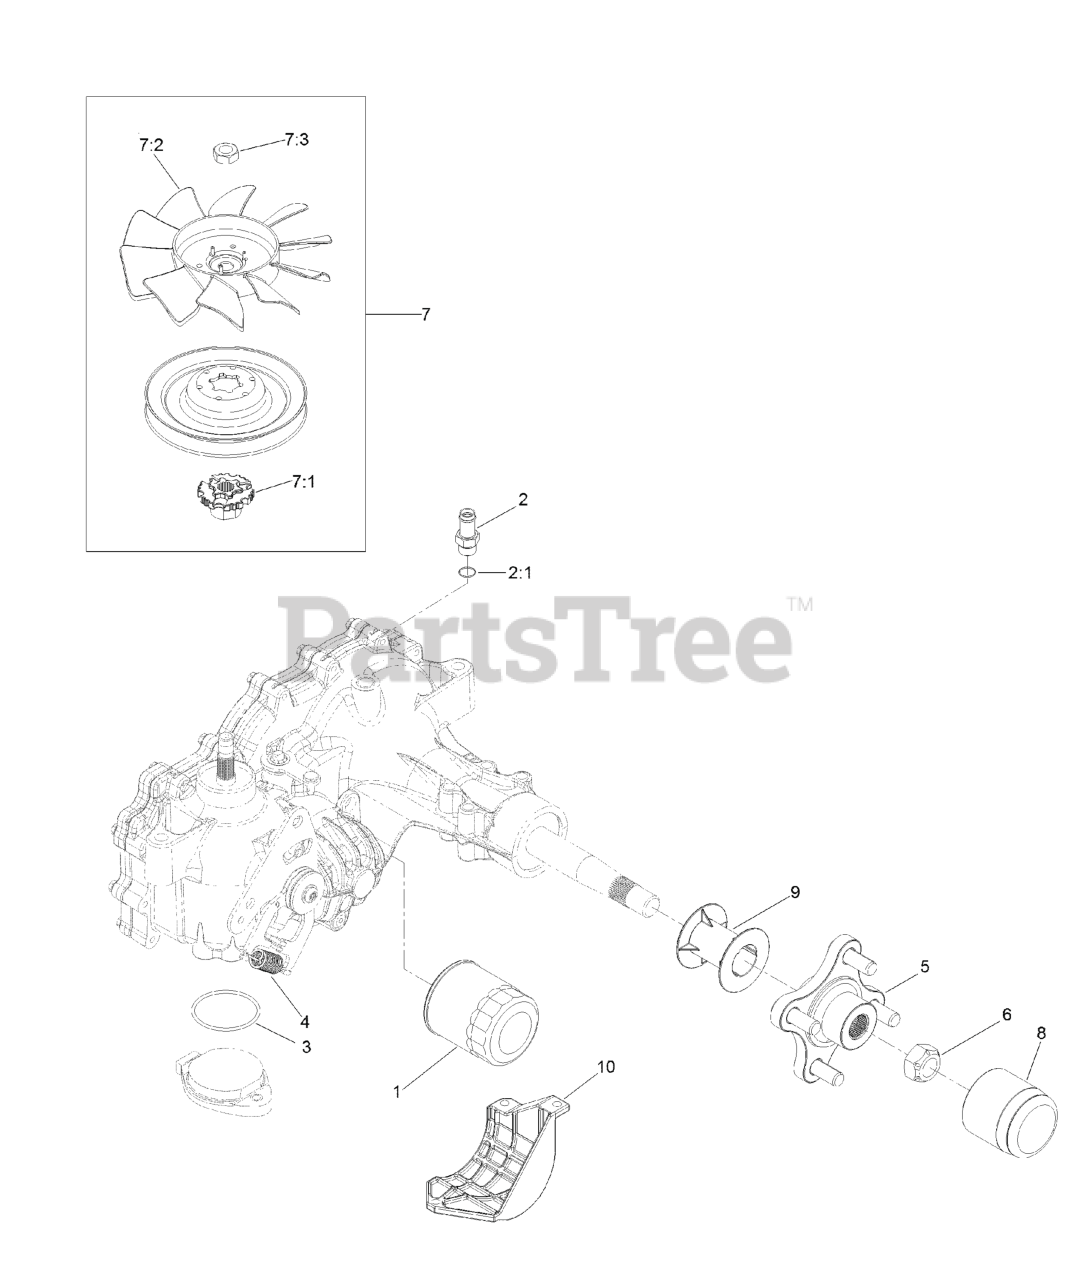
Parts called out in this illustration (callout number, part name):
1	ELEMENT-OIL FILTER, HYD
2	ADAPTER-STRAIGHT
2:1	O-RING
3	O RING-SEAL
4	SPRING-EXTENSION
5	HUB-OFFSET
6	NUT-HUB
7	FAN AND PULLEY KIT
7:1	HUB-FAN
8	CAP-AXLE, LONG
9	TUBE-AXLE
10	GUARD-FILTER, LH
